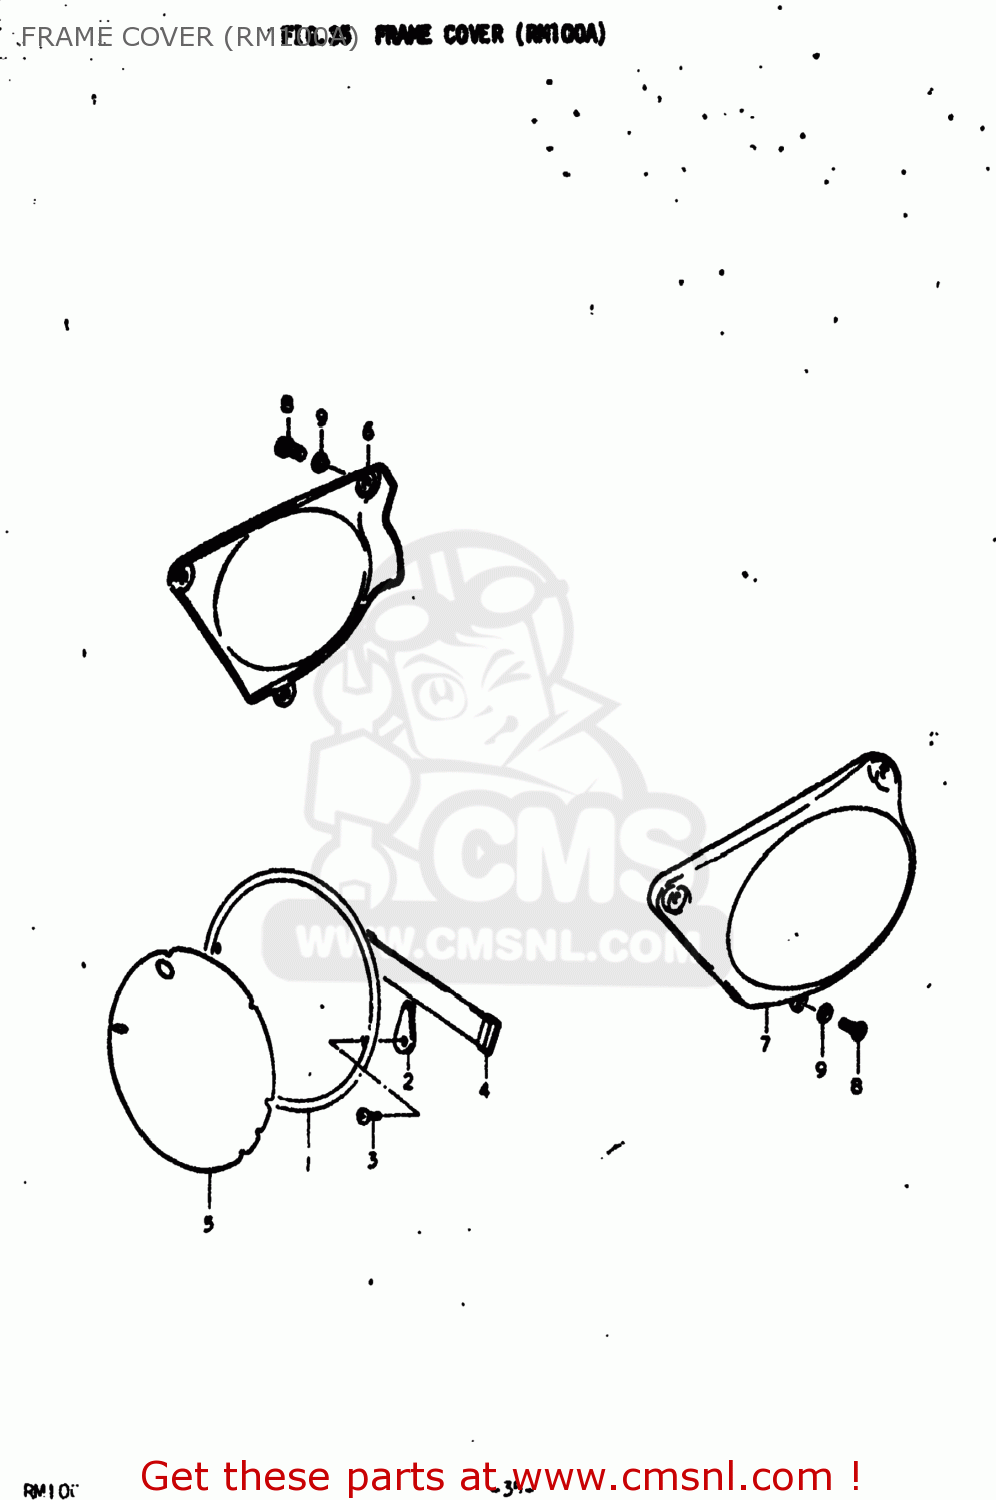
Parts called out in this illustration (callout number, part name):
1	PLATE SET,FRONT
3	SCREW 6X12
4	BAND
5	EMBLEM,FRONT NUMBER PLATE
6	COVER,FRAME,RIGHT
7	COVER,FRAME,LEFT
8	SCREW 6X12
9	WASHER
